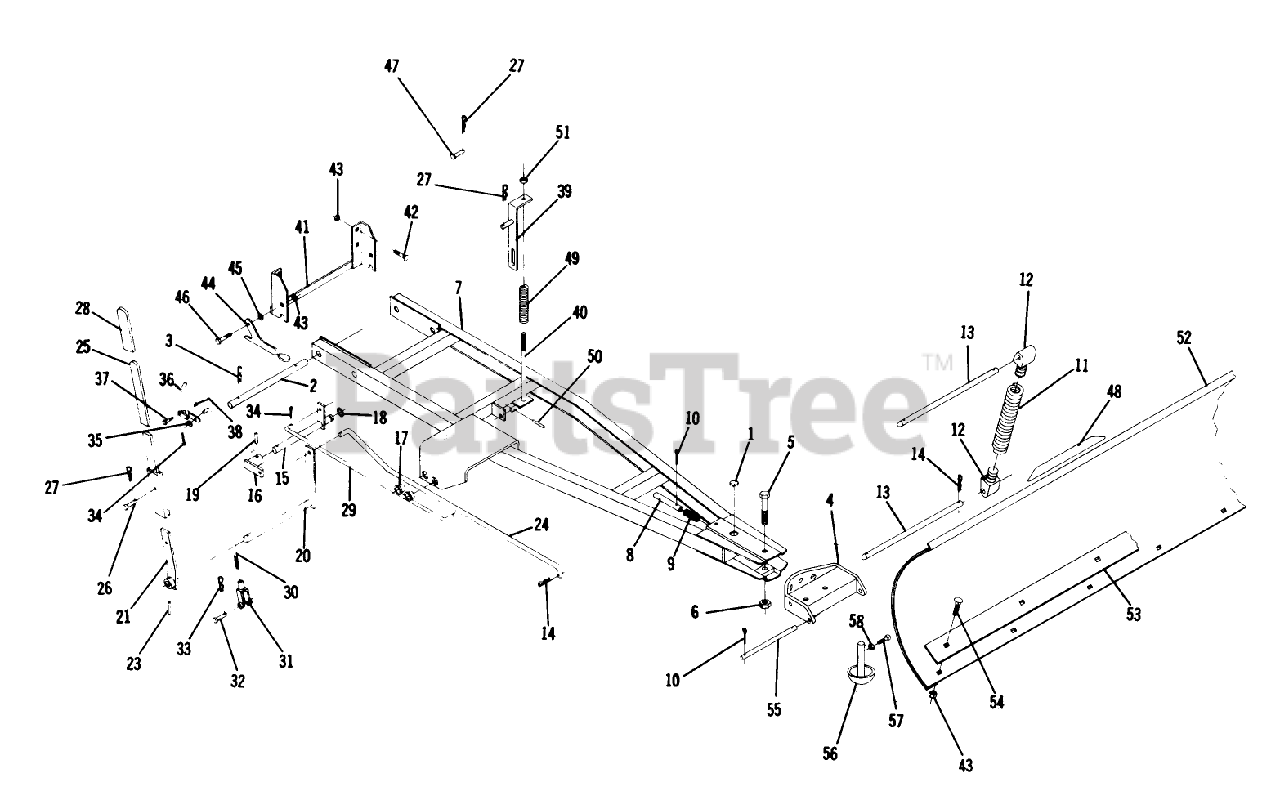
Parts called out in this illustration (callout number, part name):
1	PLUG
3	Hairpin
9	SPRING-COMPRESSION
14	Hairpin
17	BUSHING
23	SPIROL PIN 3/8X1 1/2
27	Hairpin Cotter
28	GRIP
44	PLATE-LATCHING
50	Spirol Pin
55	ROD-LOWER
56	SKID SHOE ASSY *R
